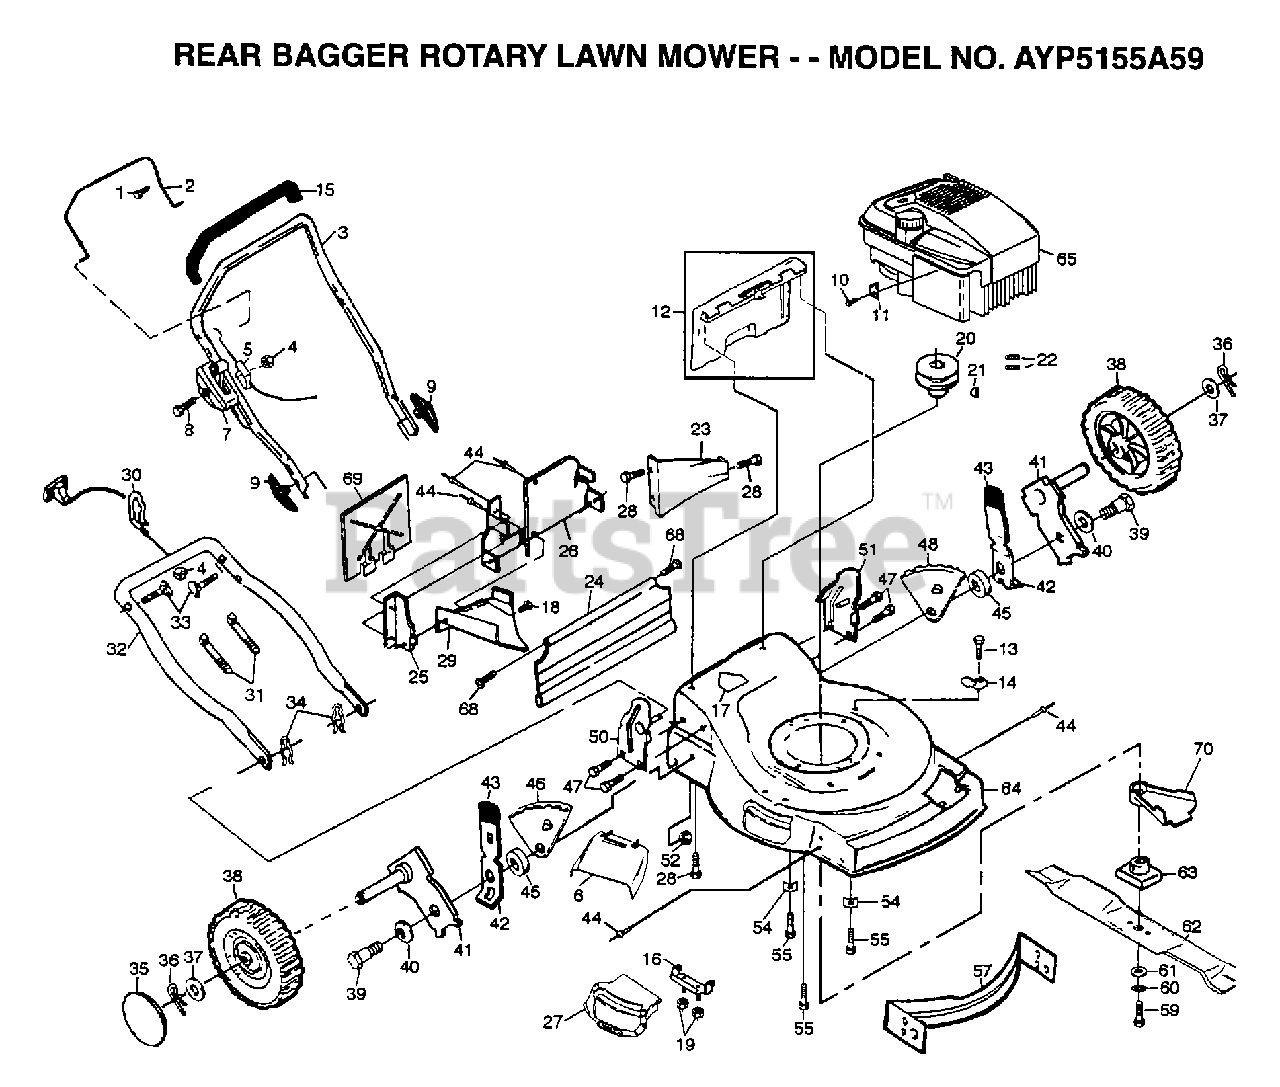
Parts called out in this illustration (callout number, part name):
1	"SCREW,PAN HD"
2	"BAR,CONT"
5	"CABLE,ENG ZONE CO"
6	GUARD.DISCH.CLIPO
7	"CONTROL, THROTTLE"
8	SCREW.HXHD.WASH.
9	KNOB PM
10	SCREW PM
11	CABLE CLAMP
12	KIT.DOOR.REAR.22
13	TAPPING SCREW
14	GUIDE CLIP PM
16	BRACKET.HINGE.W/F
17	DECAL-DANGER PM
18	SCREW PM
20	ENGINE.PULLEY.FWG
21	HI PRO KEY PM
22	SCREW
23	REAR BAFFLE
24	SKIRT.REAR.FGD.22
26	PLATE.BACK
27	DOOR.MULCH.COMBI
28	SCREW
29	DISCHARGE BAFFLE
30	ROPER GUIDE PM
33	BOLT.HANDLE.LM
34	HAIRPIN COTTER
35	HUB CAP
36	RETAINER CLIP PM
37	WASHER
39	BOLT SHLD 3/8-16
40	"WASHER, BELLEVIL."
41	AXLE ARM
42	SPRING SELECTOR
43	KNOB PM
44	BLIND RIVET
46	BRACKET.ADJ.9.RH
47	SCREW
48	BRACKET.ADJ.9.LH
52	LOCKNUT PM
55	SCREW
59	SCREW
60	LOCKWASHER
61	"WASHER,HARDEN"
62	"BLADE.MULCH.22"""
63	ADAPTOR.BLADE.LM
64	KIT.HSG.22RD.FWGD
68	HINGE SCREW
69	MULCHER PLATE
